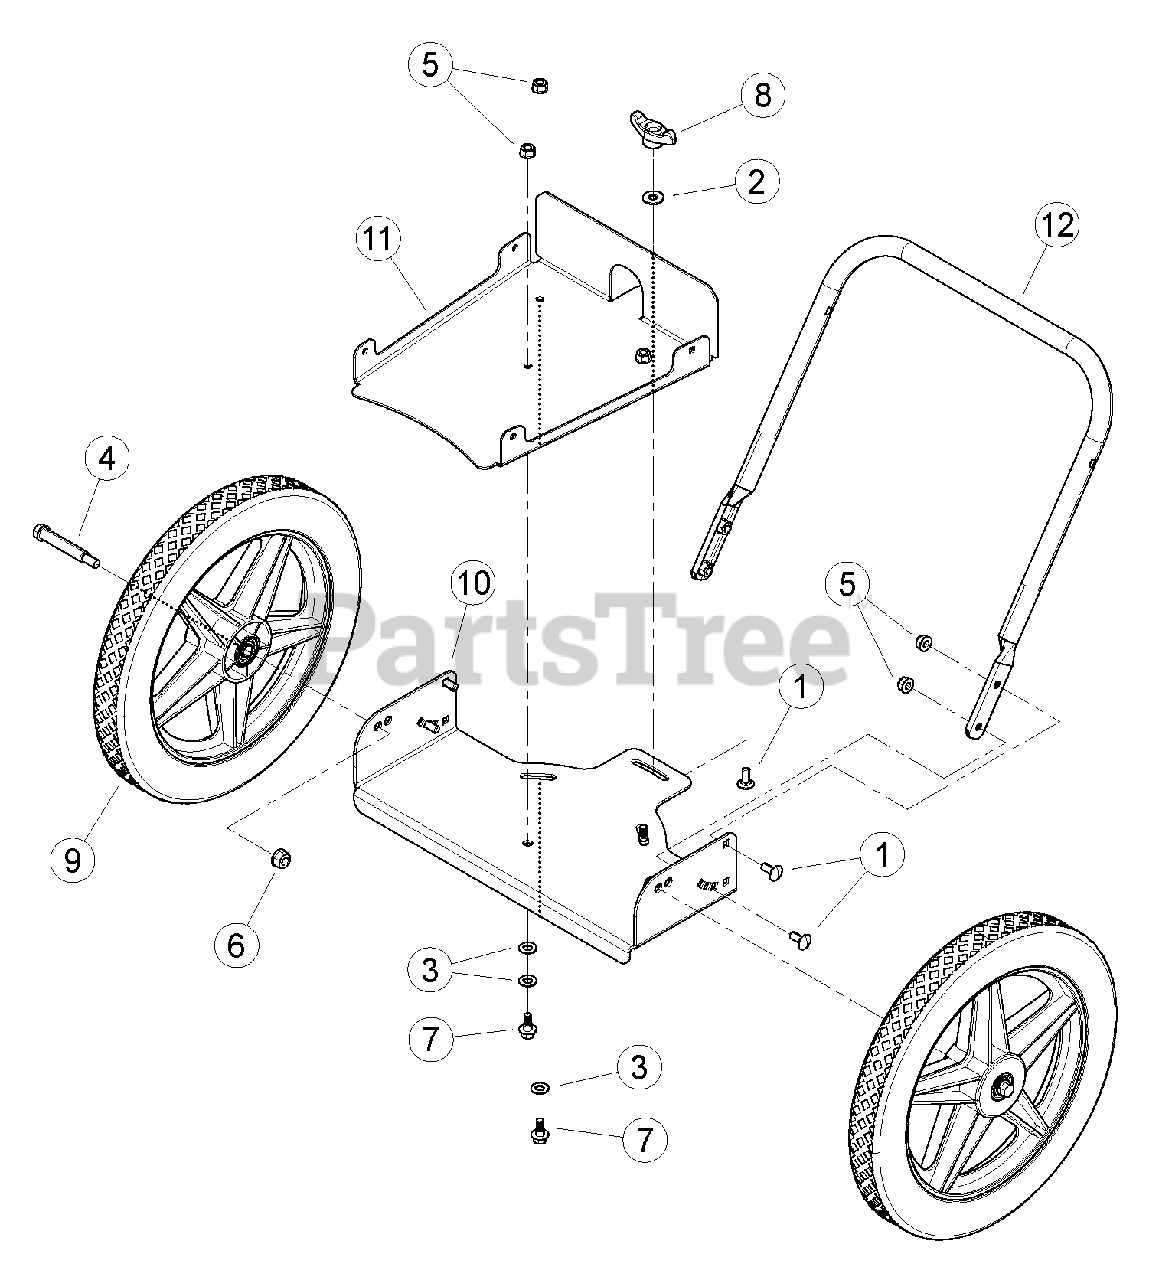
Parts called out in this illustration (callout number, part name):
1	BOLT, 5/16-18 X 3/4 SN GR5 CRG
2	WASHER, 5/16 FLAT
3	WASHER, NYLON .390 ID X .750 OD
4	BOLT, 3/8-16 X 3-1/4 FLANGED SHOULDER
5	NUT, 5/16-18 NYLOCK FLANGE
6	NUT, 3/8-16 NYLOCK FLANGE
7	BOLT, 5/16-18 X 3/4 ZP FLANGE SHOULDER
8	KNOB, 5/16-18 FEEM TEE
9	WHEEL, TRIMMER 15 X 1.75
10	PLATE, TRIMMER AXLE
11	PLATE, TRIMMER BASE PUSH
12	HANDLE BAR, LOWER TRIMMER PAINTED
